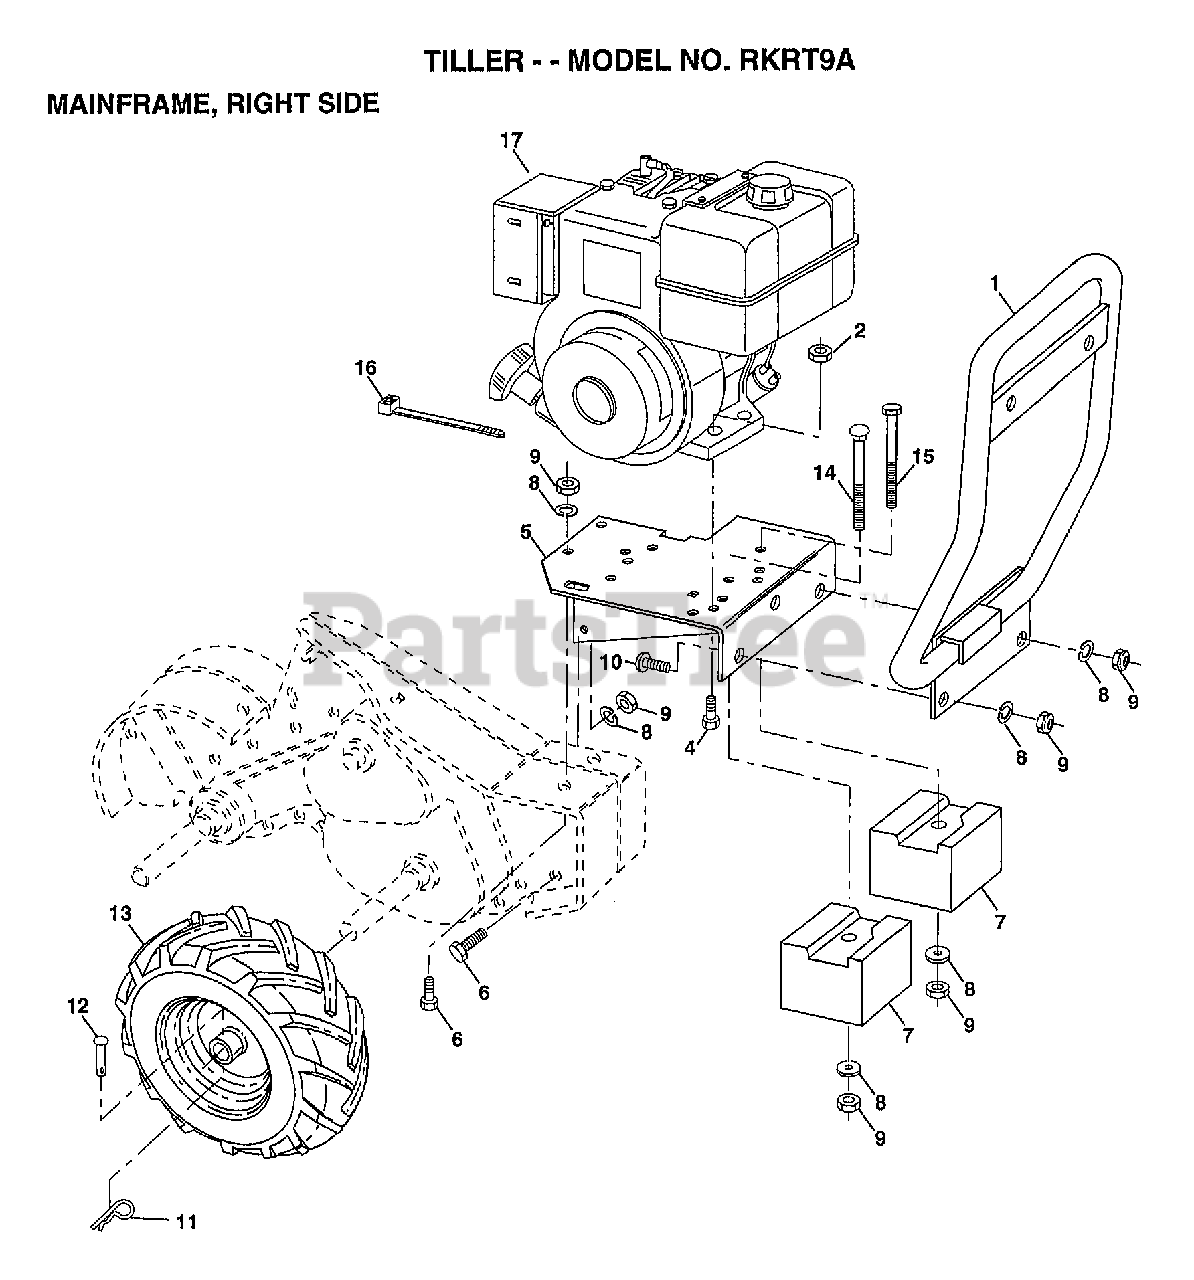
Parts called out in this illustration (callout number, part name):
1	BUMPER.ASM
4	BOLT
5	"ASM. ENGINE, BASE"
6	BOLT
7	COUNTERWEIGHT CRT
8	LOCKWASHER
9	NUT.HEX.3/8-16UNC
11	SPRING.RETAINER
12	RIVET.PAN HD.1.75
13	TIRE TI
13	RIM.16X4X8.WHT
14	BOLT CRT
15	BOLT.3/8-16X4.5
16	WIRE TIE
